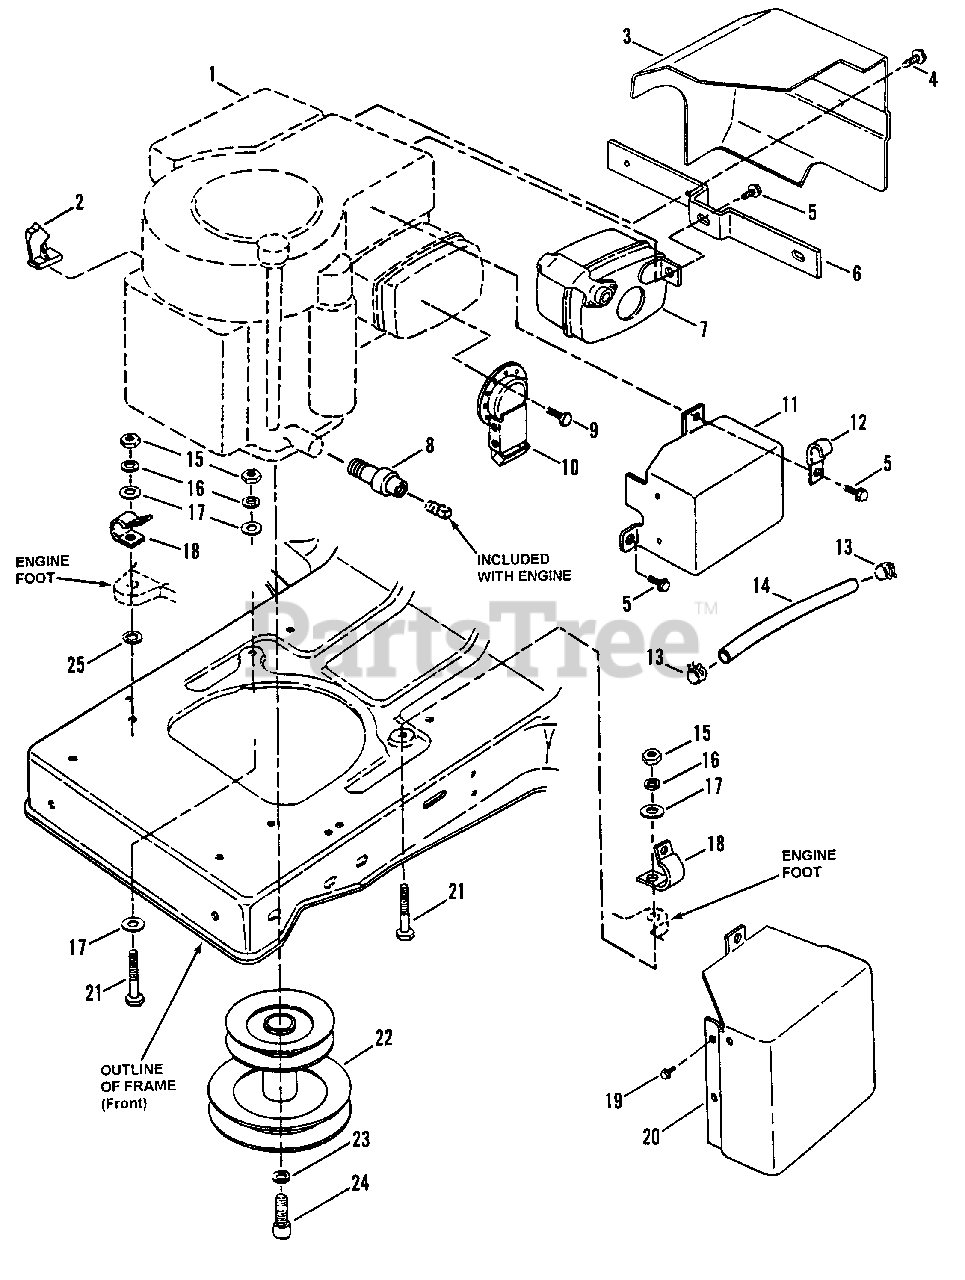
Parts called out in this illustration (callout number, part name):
2	CLIP, Speed
3	HEAT SHIELD
4	SCREW, #10-24 x 1/2" Hex Washer Self-Tap (Torx)
5	BOLT, 1/4-20 x 1/2" Hex Flange Lock
6	BRACKET, Heat Shield
7	MUFFLER, Exhaust
8	EXTENSION, Oil Drain (Shown)
9	SCREW, #8-18 x 1/2" Hex Head, Self-Tapping
10	EXTENSION, Muffler
11	HEAT SHIELD, Muffler
12	CLIP, "J" Type
13	CLAMP, Fuel Line
14	LINE, Fuel, 16" Long
14	LINE, Fuel, 7" Long
15	NUT, 5/16-18 Hex
16	WASHER, 5/16 Split Lock
17	WASHER, 5/16 Flat
18	CLIP, Wiring Harness
19	SCREW, #10-24 x 5/8" Hex Washer Head, Self-Tapping
20	HEAT SHIELD, Muffler (Shown)
21	SCREW, 5/16-18 x 1-3/4" Hex Head Cap
22	ASSEMBLY, Engine Pulley
23	WASHER, 7/16 Split Lock
24	SCREW, 7/16-20 x 1" Hex Cap, Socket Head
25	WASHER, 5/16 Internal Tooth Lock
